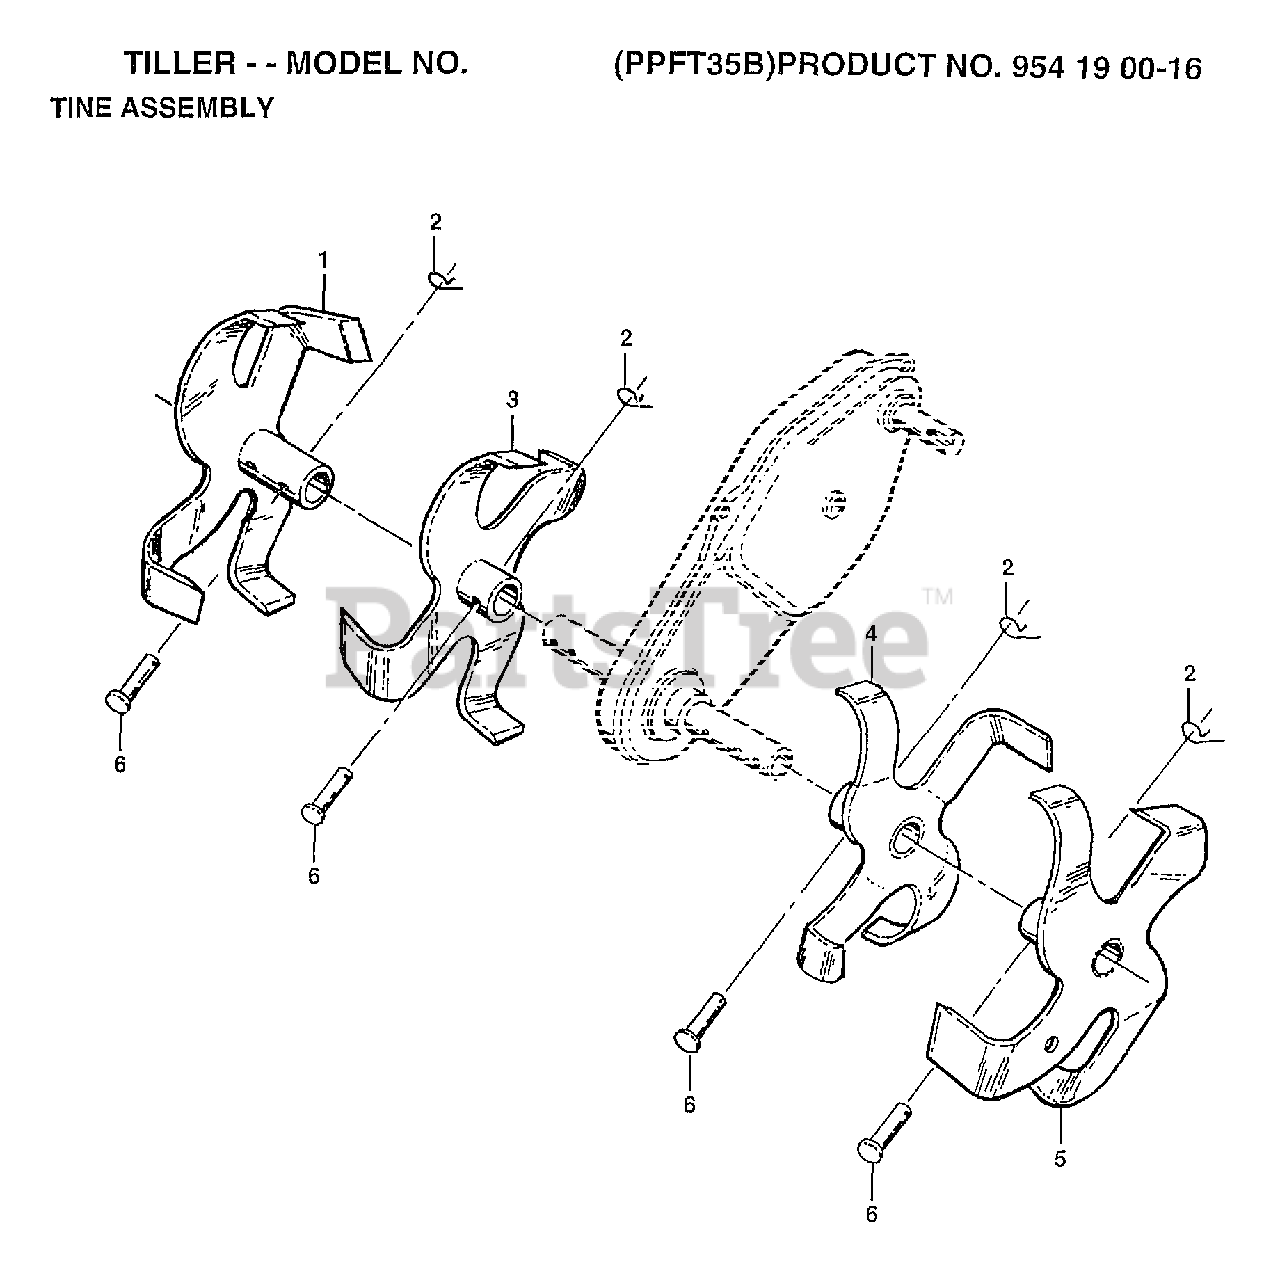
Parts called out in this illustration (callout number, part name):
1	TINE ASSY RH
2	SPRING.RETAINER
3	TINE ASSY RH
4	TINE INN LH TI
5	TINE ASS'Y LH
6	DRILLED RIVET RT
